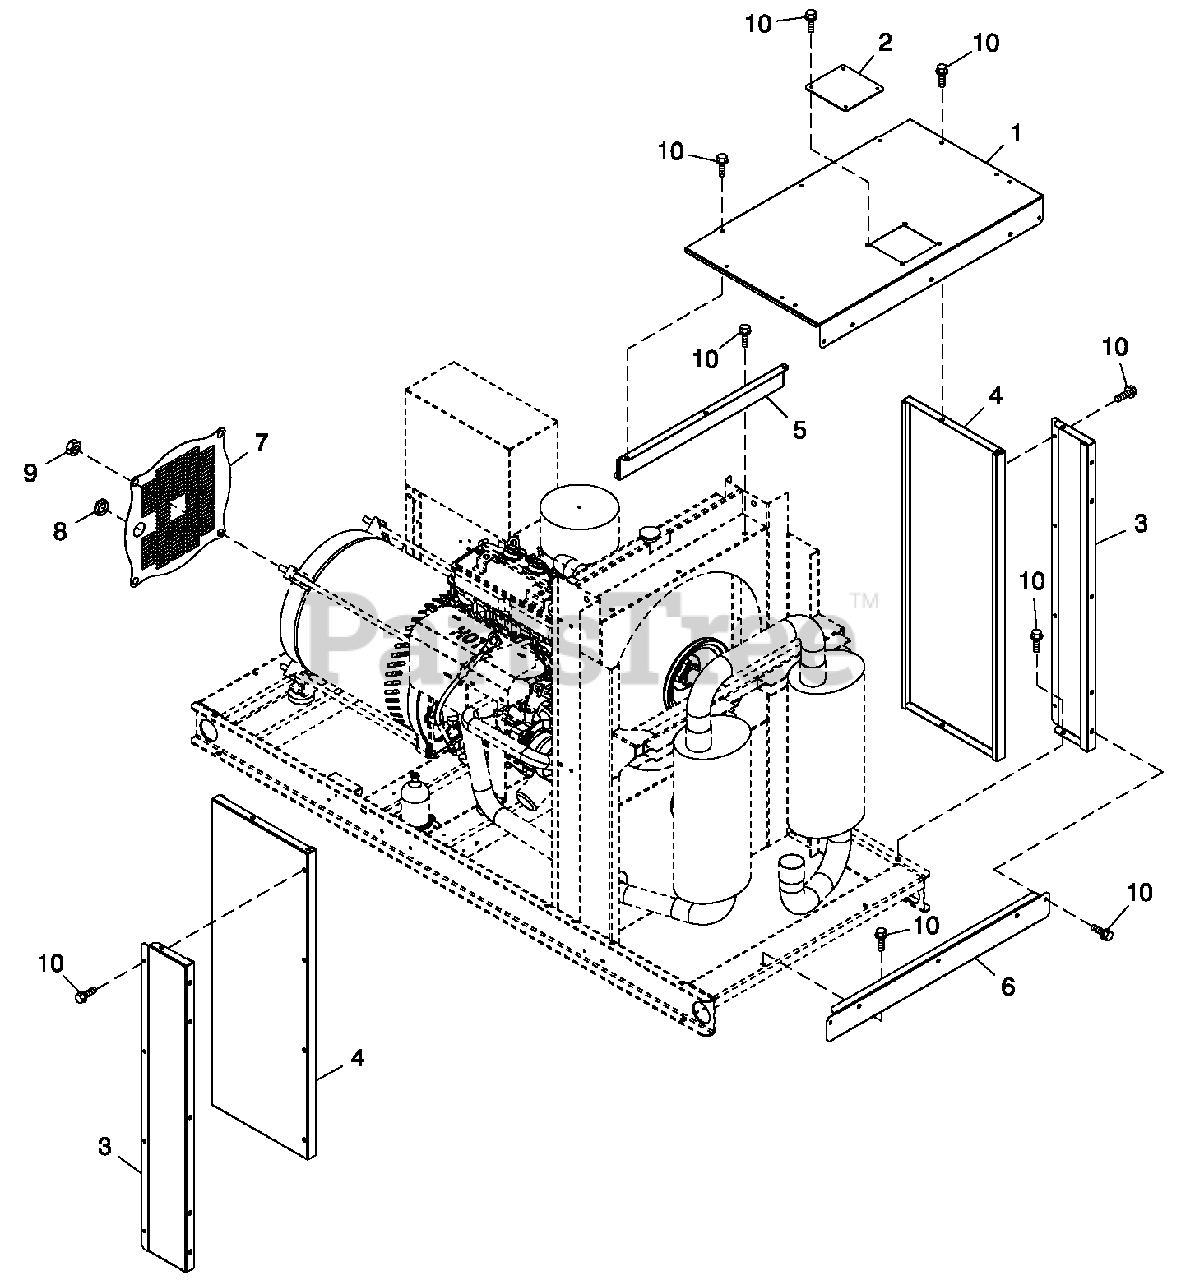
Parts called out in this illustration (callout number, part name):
1	PANEL TOP QTA C2
2	ACCESS COVER 160 X 170 GALV
3	PANEL SIDES FRONT QTA C2
4	PANEL REAR SIDES QTA C2
5	PANEL TOP MOUNT QTA C2
6	PANEL LOWER FRONT QTA C2
7	GUARD REAR ALT
8	BUSHING SNAP SB-2.5-31
9	NUT HEX M14-2.0 G8 YEL CHR
10	SCREW THF M6-1 X 16 N WA Z/JS
